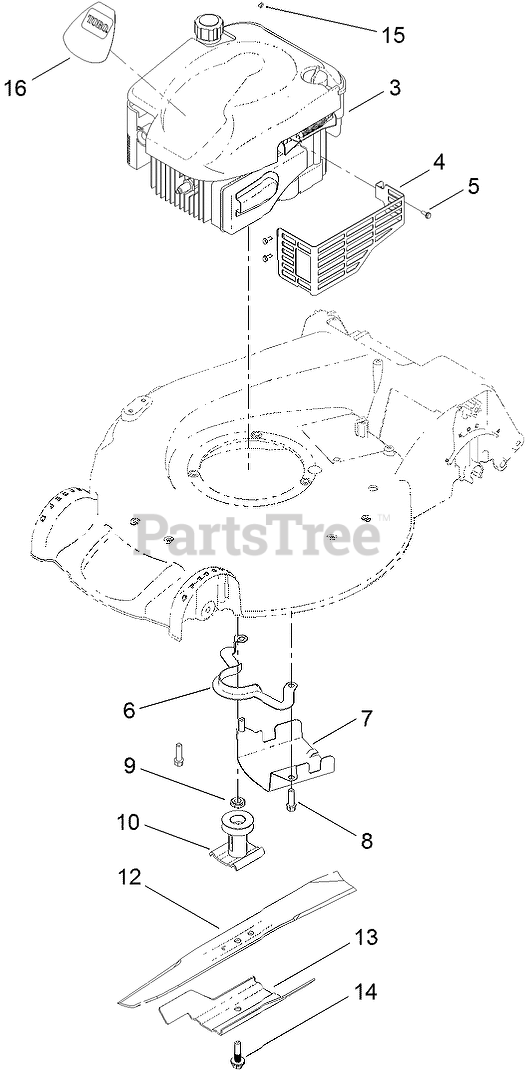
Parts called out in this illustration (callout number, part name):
4	SHIELD-MUFFLER
5	SCREW-TAPTITE
6	GUIDE-BELT
7	SHIELD-GRASS
8	SCREW-TAPTITE
9	Spacer-Driver
10	DRIVER-BLADE
12	BLADE-RECYCLING
13	Accelerator-Blade
14	BOLT-BLADE
15	STOP-ROPE
16	DECAL-SHROUD
